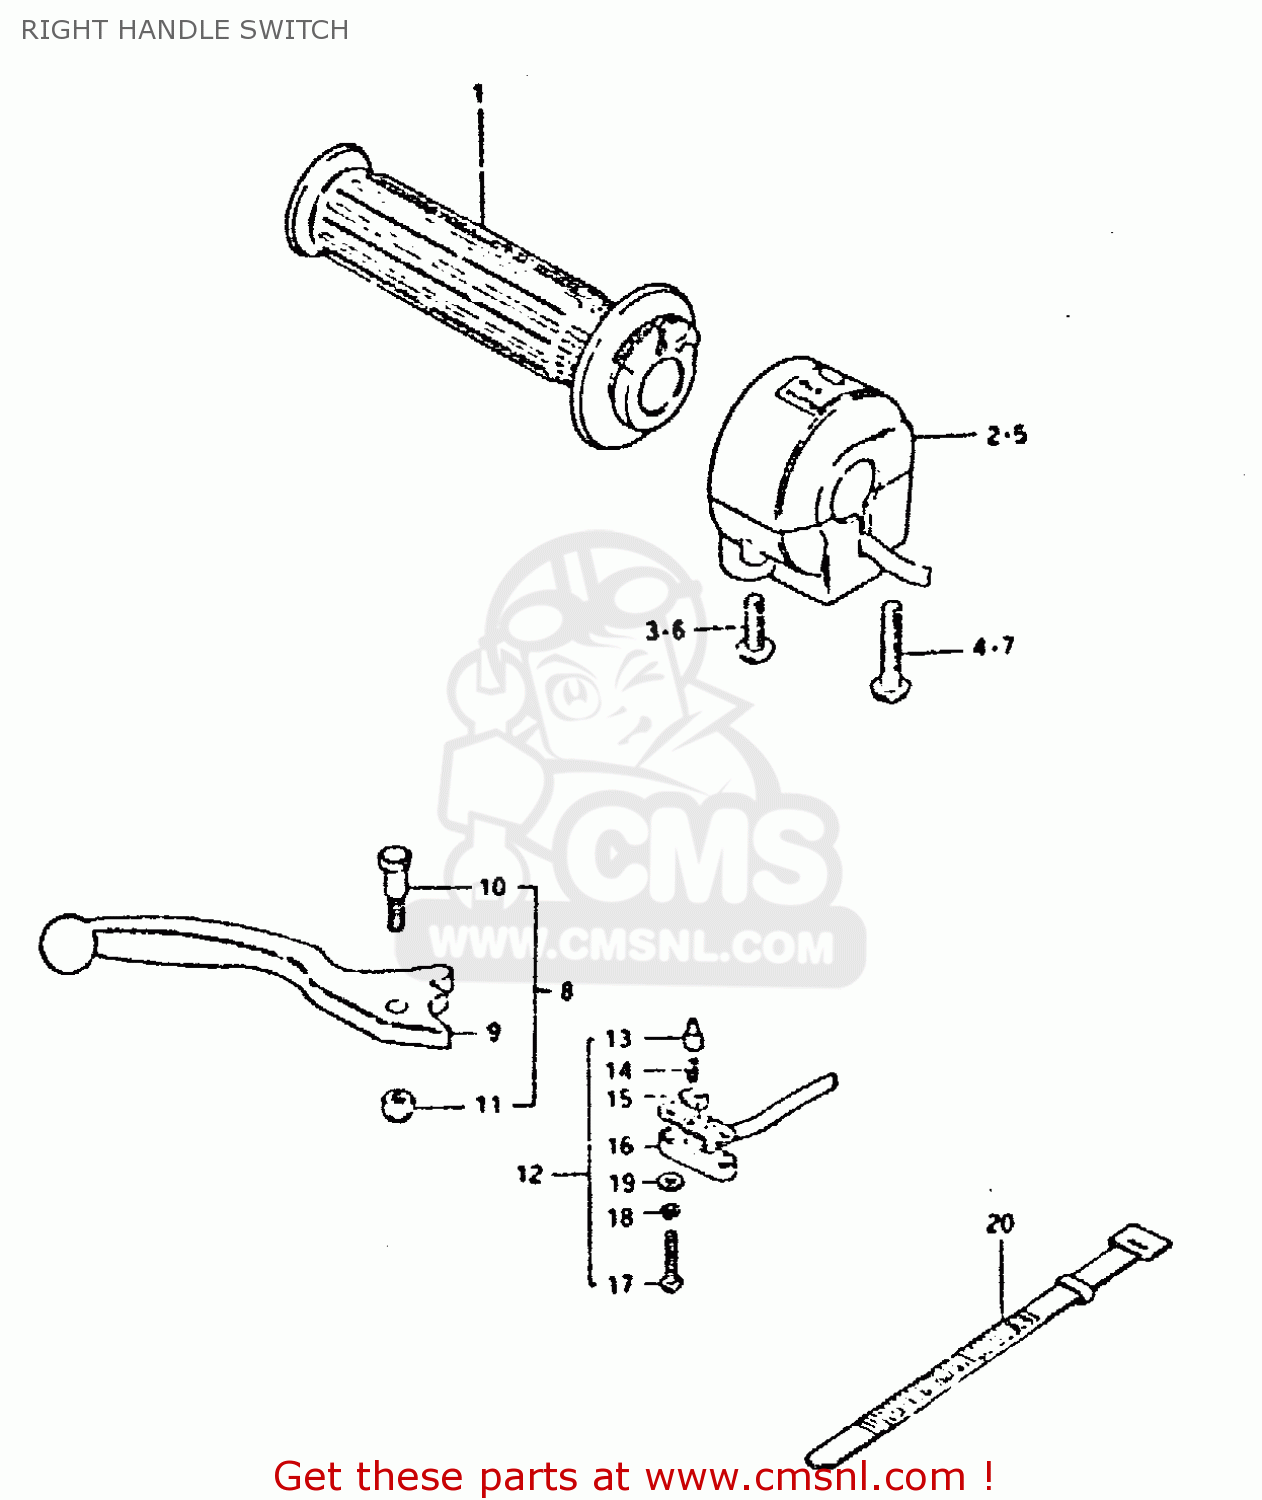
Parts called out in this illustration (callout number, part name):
1	GRIP,THROTTLE
2	SWITCH ASSEMBLY,HANDLE,RIGHT
3	SCREW
4	SCREW
8	LEVER ASSEMBLY,BRAKE
9	LEVER,BRAKE
10	BOLT
11	NUT 6MM
20	CLAMP(L:120)
